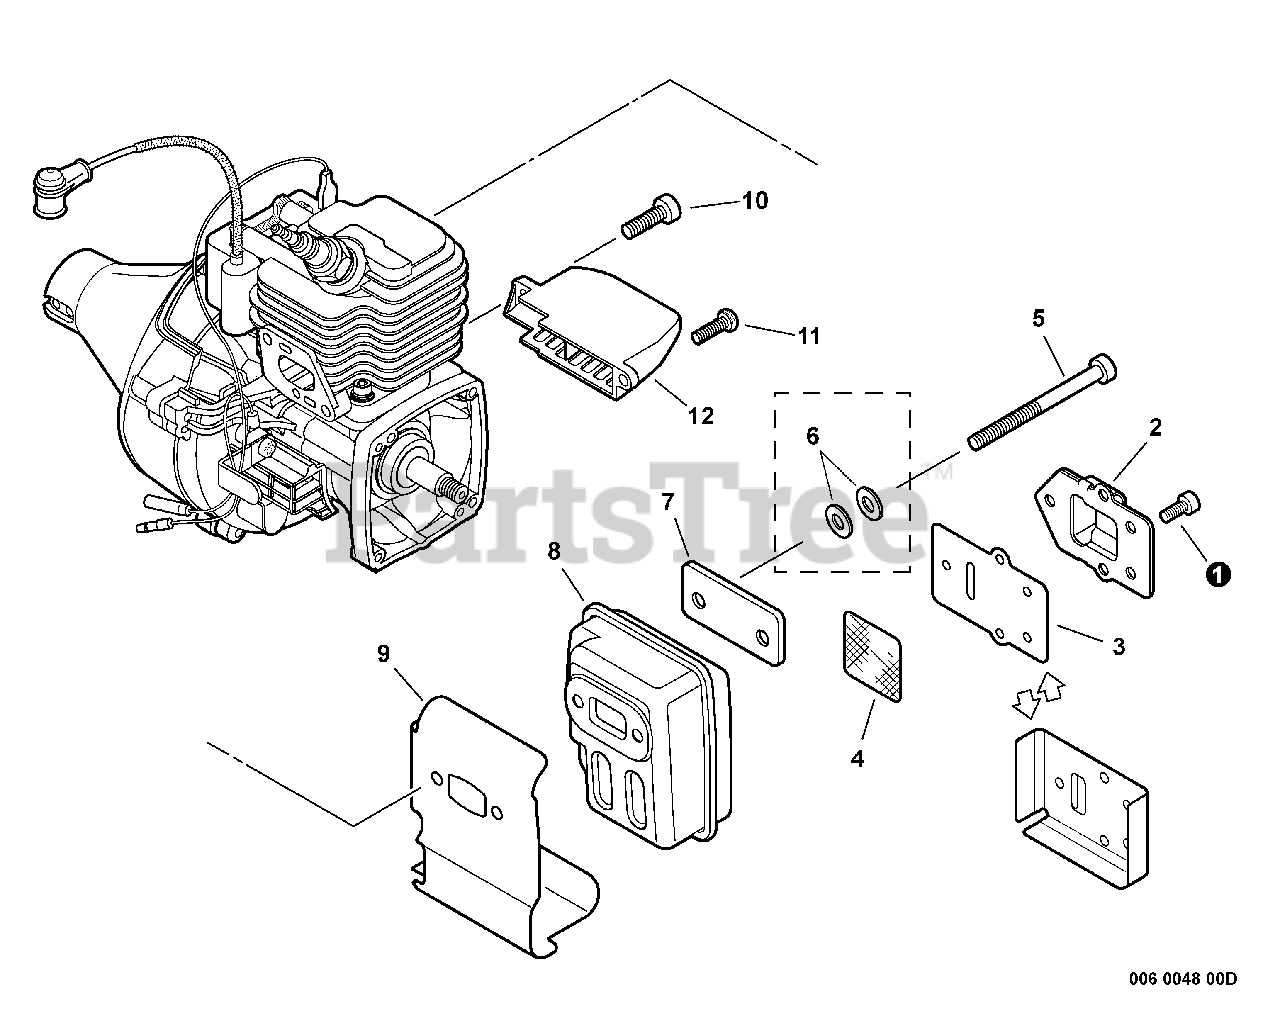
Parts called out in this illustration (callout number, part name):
1	BOLT, TORX 4×8
2	GUIDE, EXHAUST
3	GASKET, EXHAUST
4	SCREEN, SPARK ARRESTER
5	BOLT, TORX 5×55
7	PLATE, EYE
8	MUFFLER
9	HEAT SHIELD, EXHAUST
10	BOLT, TORX 5×16
11	BOLT, TORX 5×16
12	COVER, MUFFLER
